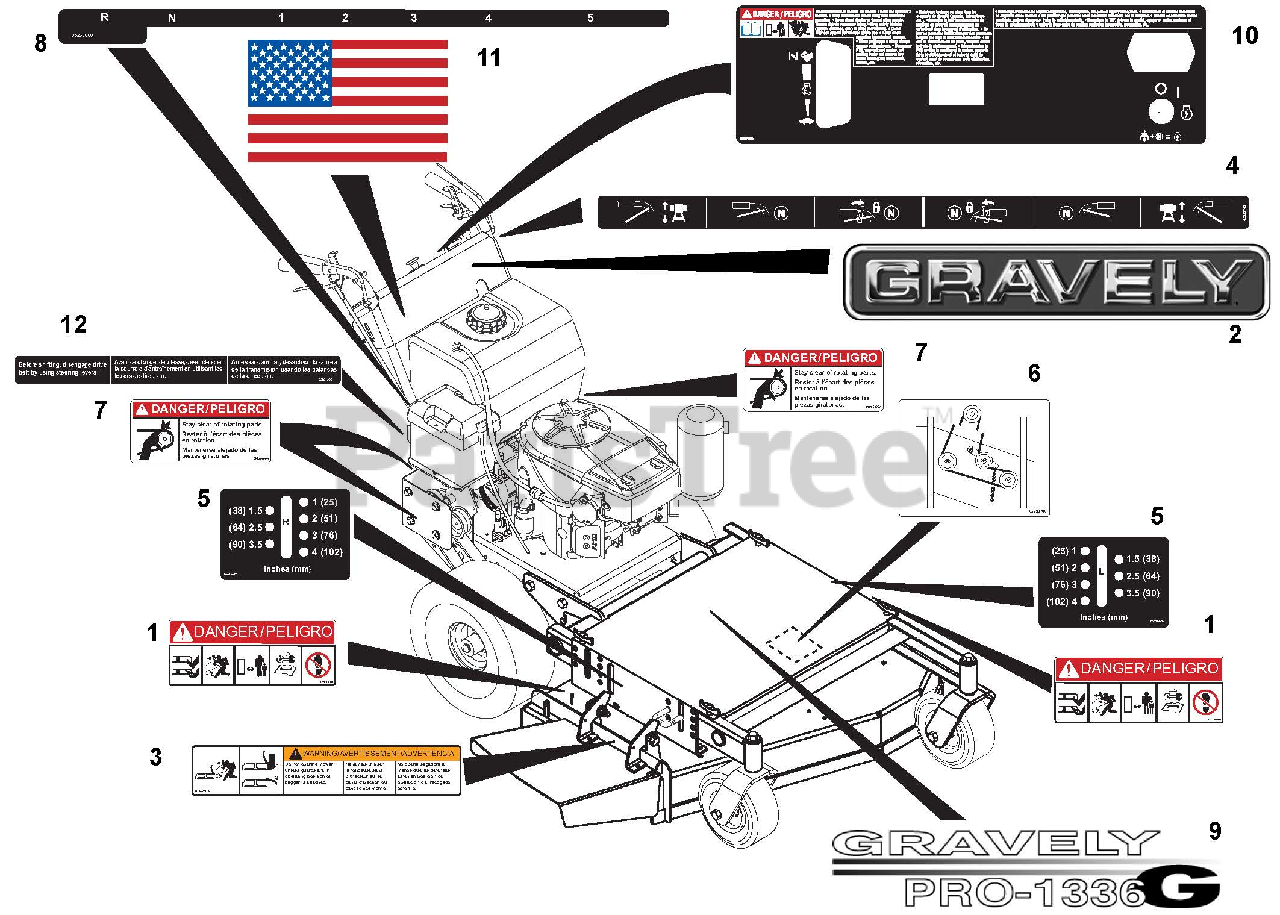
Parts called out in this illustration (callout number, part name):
1	Decal, Mower Pan Head Danger
2	Decal- 15" Gravely Logo
3	Decal, Warning
4	Decal, Steer Levers
4	Decal-Steer Levers-Gear-Pro Steer
5	Decal-Height of Cut-Fixed- Right Hand
5	Decal-Height of Cut-Fixed- Left Hand
6	Decal-Belt Diagram-2 Spindle
6	Decal-Belt Diagram-3 Spindle
7	Decal-Danger-Belt Rotating
8	Decal-Shift Lever
9	Decal-Pro 1336G
9	Decal-Pro 1536G
9	Decal-Pro 1548G
9	Decal- Pro 1332G
9	Decal- Pro 1544G
10	Decal, Control GR13
10	Decal, Control GR15
10	Decal, Control GR13-Pro Steer
10	Decal, Control GR15-Pro Steer
11	Decal, American Flag
12	Decal, Declutch
